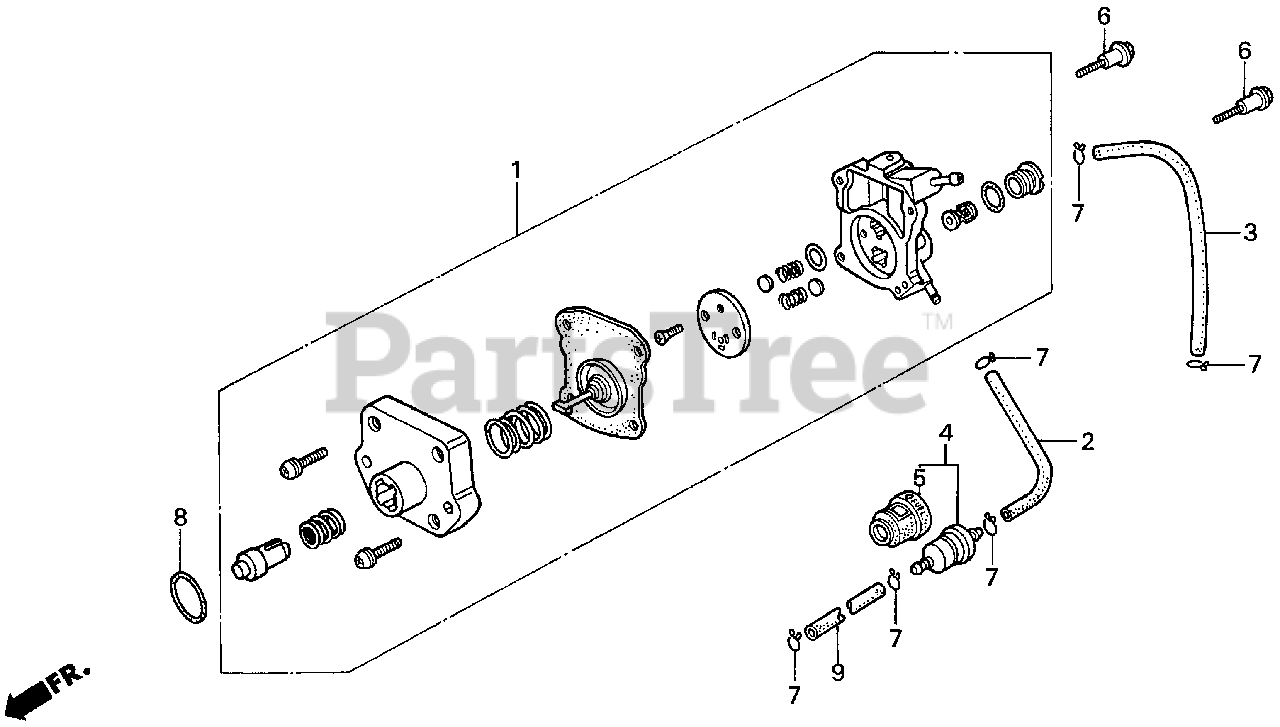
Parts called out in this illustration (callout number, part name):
1	PUMP ASSY., FUEL
2	TUBE, FUEL (4.5MM)
3	JOINT, FUEL TUBE
4	FILTER, FUEL
5	SUSPENSION, STRAINER
6	BOLT, SPECIAL (6X34)
7	CLIP, TUBE (B8)
8	O-RING (20.8X2.4)
9	BULK HOSE, FUEL (4.5X3000) (4.5X265)
